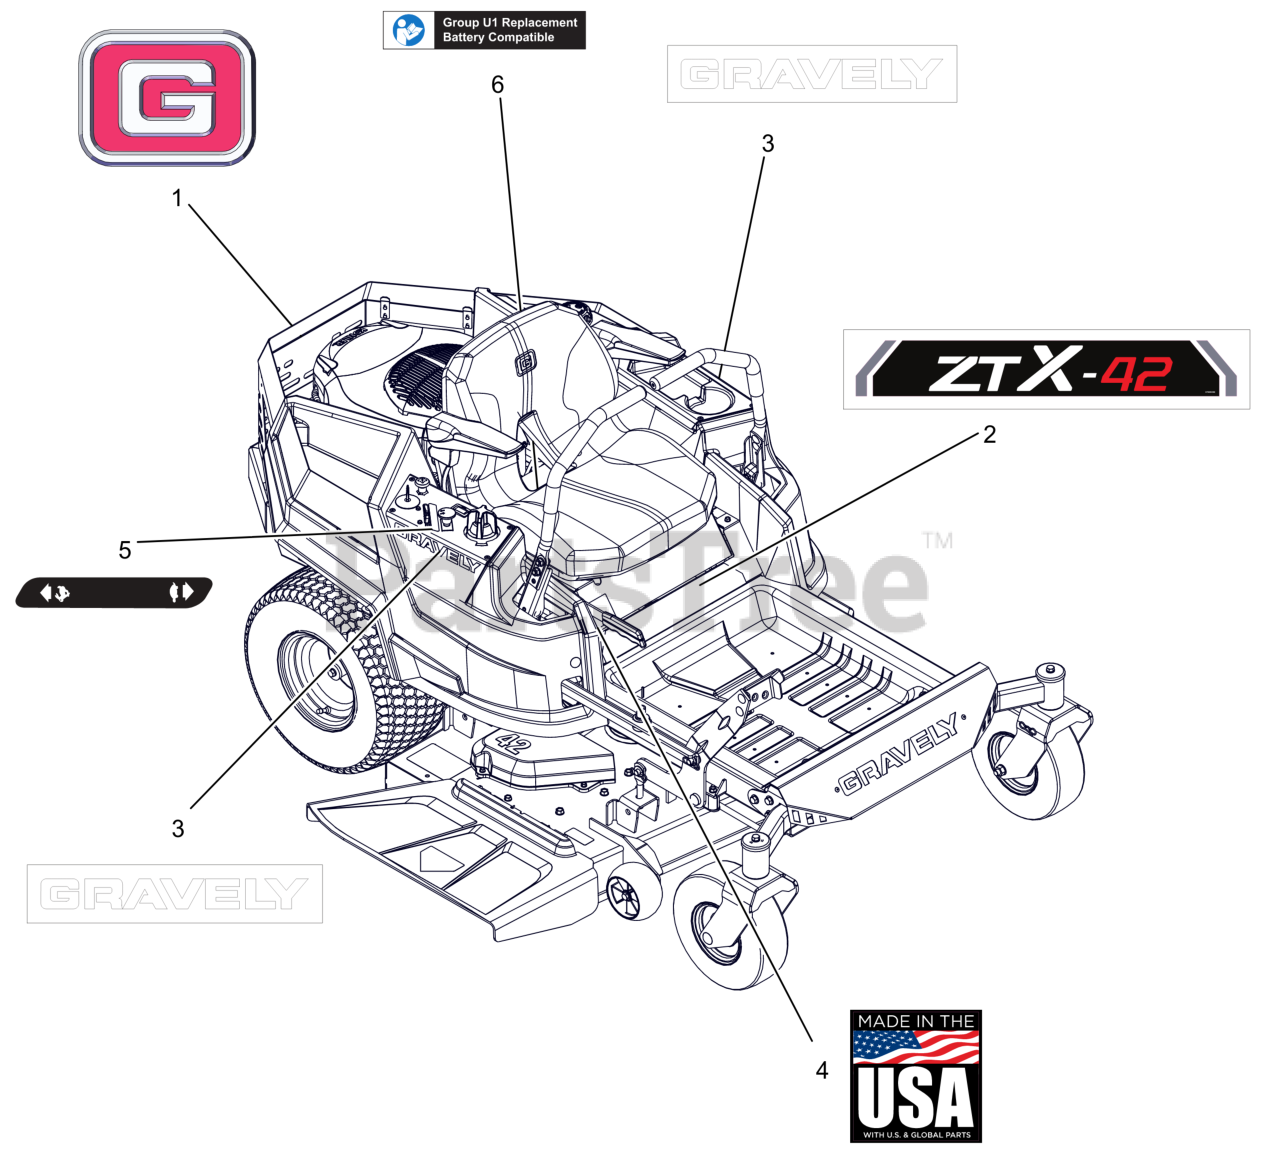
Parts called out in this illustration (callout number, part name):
1	DECAL, GRAVELY BRAND
2	DECAL, GRAVELY ZT X 42
3	DECAL, 9.5" GRAVELY LOGO
4	DECAL, MADE IN USA
5	DECAL, DASH DECAL
6	DECAL, U1 BATTERY REPLACEMENT
